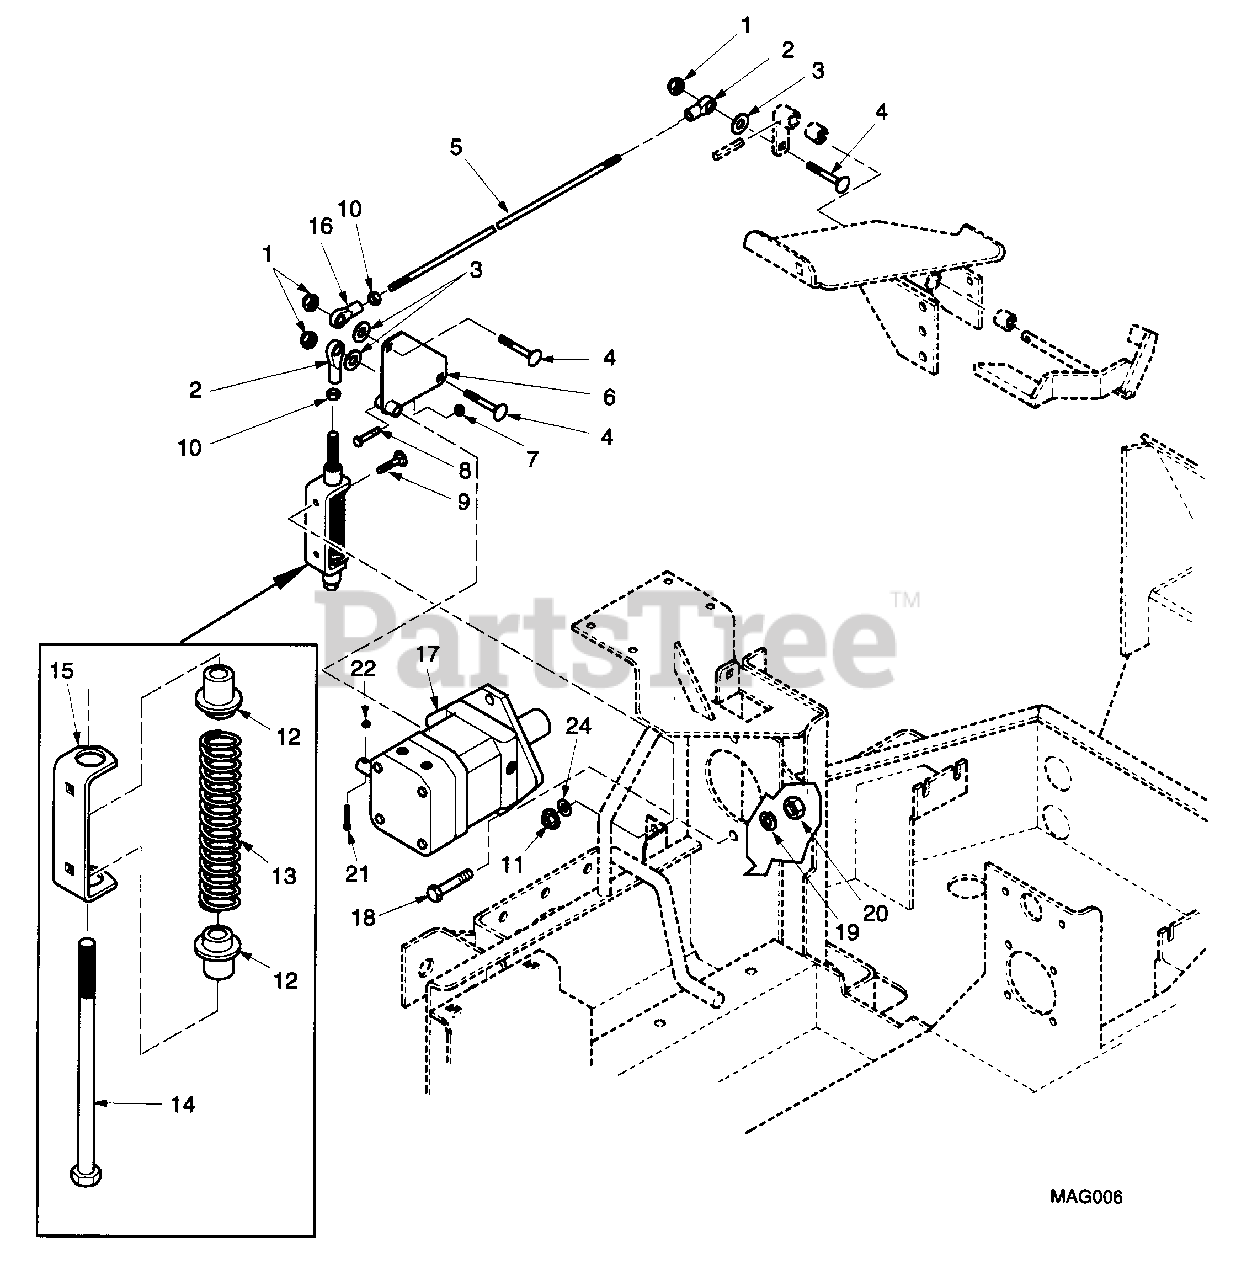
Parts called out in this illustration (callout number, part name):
1	HEX LOCKNUT, ELASTIC STOP, 3/8-16
2	BALL JOINT, 3/8-24 LH THREAD
3	FLATWASHER, 3/8(.391 X .938 X .105)
4	CARRIAGE BOLT, 3/8-16 X 1-1/2
5	ROD, TRANSMISSION CONTROL
6	BELLCRANK, PUMP CONTROL
7	HEX LOCKNUT, ELASTIC STOP, 1/4-20
8	BOLT, HEX HEAD, 1/4-20 X 1-1/4
9	CARRIAGE BOLT, 5/16-18 X 1
10	HEX NUT, 3/8-24
11	SERR. FL. HEX NUT, 5/16-18
12	BUSHING, SPRING KEEPER
13	SPRING, NEUTRAL RETURN
14	BOLT, NEUTRAL ADJUSTMENT, 3/8-24 X 6-3/4
15	RETAINER, NEUTRAL SPRING
16	BALL JOINT, 3/8-24 RH THREAD
17	HYDRAULIC PUMP
18	BOLT, HEX HEAD, 1/2-13 X 1-1/2
19	LOCKWASHER, 1/2
20	HEX NUT, 1/2-13
21	SCREW, ROUND HEAD, #10-32
22	HEX NUT, ELASTIC STOP, #10-32
